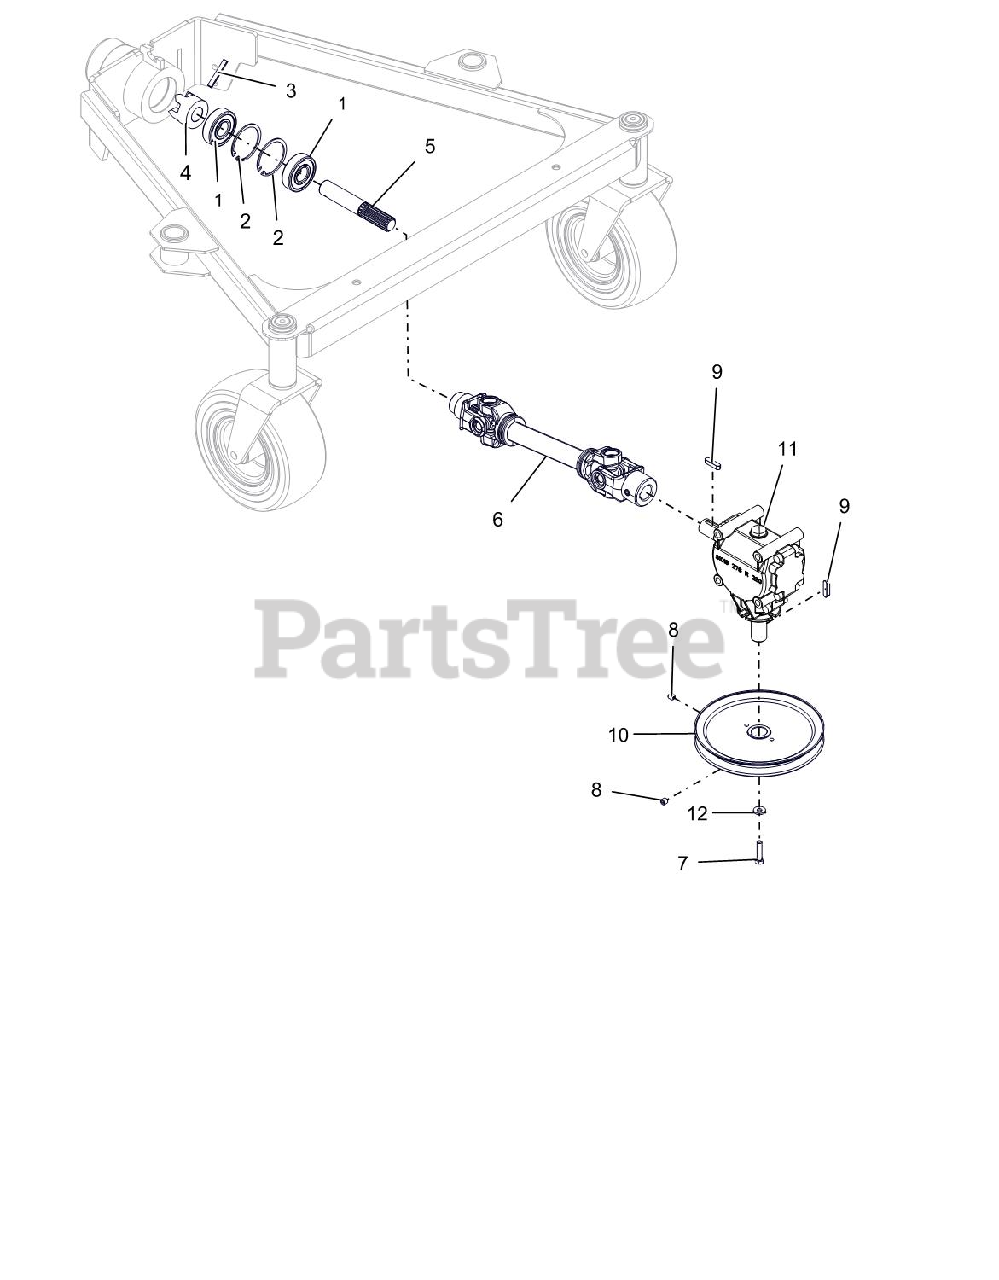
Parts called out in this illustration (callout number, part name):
1	BEARING, 6305LLC
2	RG-RTNG-INT 2.438X.078
3	PIN-ROLL 8MM X 50MM
4	CLAW COUPLING
5	PTO SHAFT
6	DRIVELINE,2-WHEEL FINISH MOWER
7	BLT, HEX M8-1.25X35 GR8.8ZC120
8	SET SCREW, 3/8-24 X 3/8 (CUP)
9	KEY-STR 8X7X32MM ROUND ENDS
10	WLDMT, PULLEY 8.25
11	GEARBOX, RH 2.78:1
12	WSHR,BLVL M8X19.84X2.5 ZCMCH
